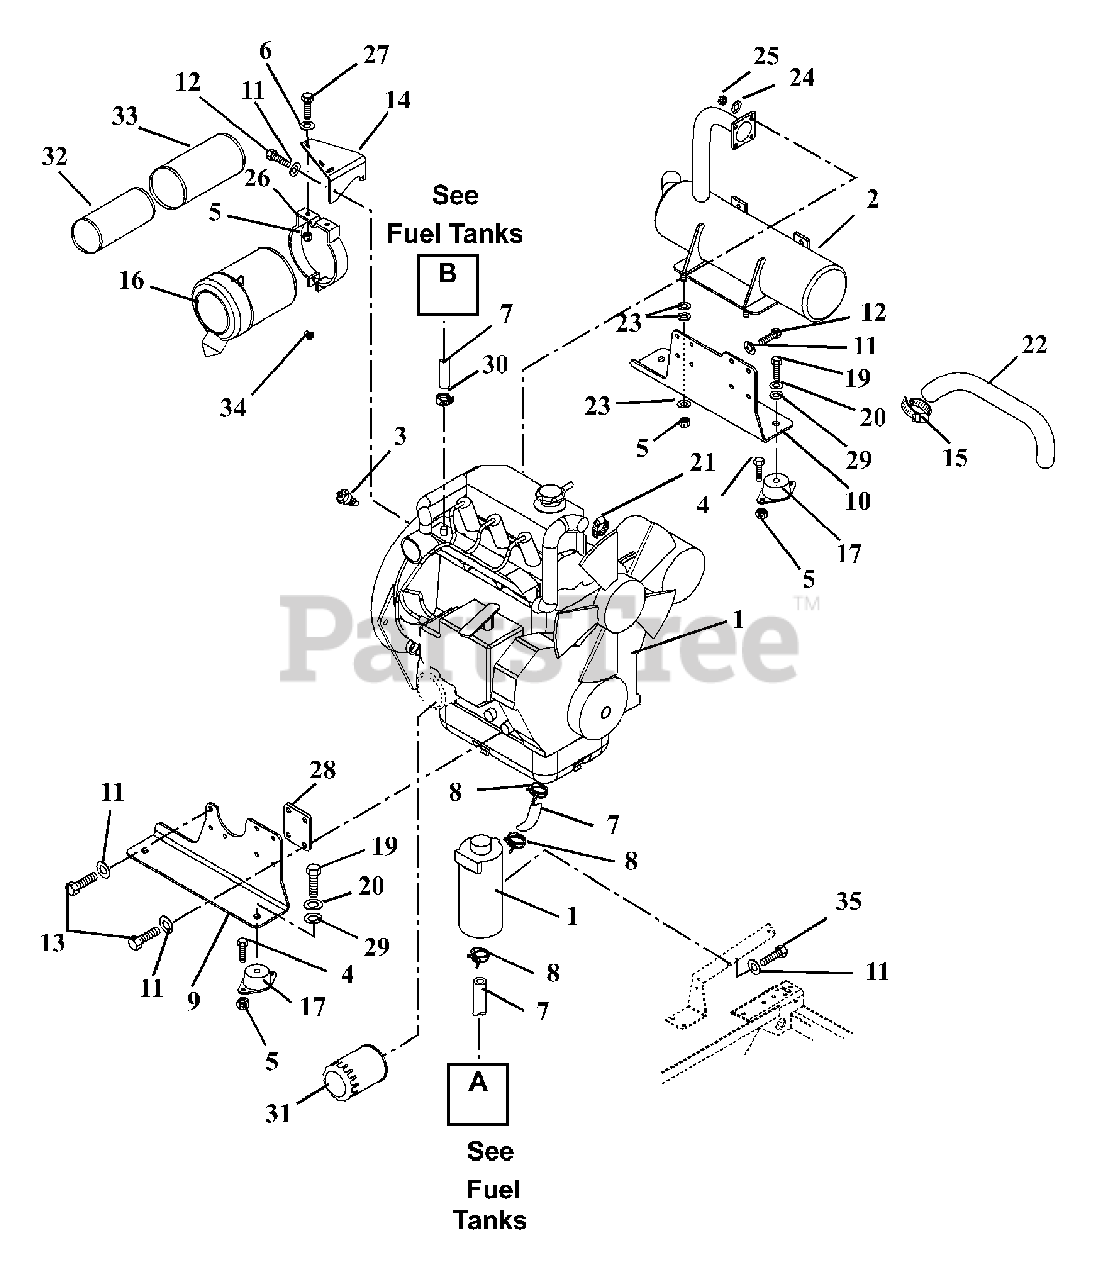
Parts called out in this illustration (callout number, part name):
1	ENGINE, 27HP DIESEL (DAIHATSU)
2	MUFFLER
3	SENDER, TEMPERATURE
4	@BLT-HEX .31-18X.75 GR5 YWZC
5	@NUT-LK-TOP-FLG .31-18 YWZC
6	@WSHR-LK .25X.062 REG YWZC
7	HOSE,5/16 ID
8	CLAMP, HOSE WIRE .520/.550
9	MOUNT, ENGINE RH (DIESEL)
10	MOUNT, ENGINE LH (DIESEL)
11	@WSHR-LK .31X.078 REG YWZC
12	@BLT-HEX M8-1.25X20 YWZC
13	BLT, HEX M8-1.25X25 GR8.8YWZC
14	BRKT, AIR CLEANER - BLACK
15	CLAMP, HOSE #32 (1.56/2.50)
16	AIR CLEANER ASSEMBLY
17	MOUNT, ENGINE, VIBRATION ISO
18	@BLT-HEX .31-18X1.00 GR5 YWZC
19	BLT-HEX .50-20X1.00 GR5 YWZC
20	@WSHR-LK .50X.125 REG YWZC
21	CLAMP-HOSE 1.50X.81X1.42
22	HOSE, AIR CLEANER
23	@WSHR-FL-STL.38X.875X.083 YWZC
24	@WSHR-LK .31X.078 REG YWZC
25	NUT-HEX M8-1.25 YWZC
26	BRACKET, AIR CLEANER MOUNT
27	@WSHR-FL-STL.38X.875X.083 YWZC
28	SPACER, ENGINE MTG (DIESEL)
29	@WSHR-FL-STL.531X1.06X.095YWZC
30	CLAMP, HOSE, IDEAL 6202 SIZE 4
31	FILTER, OIL
32	ELEMENT, INNER SAFETY
33	ELEMENT, OUTER PRIMARY
34	FTG,LUBE 45 DEG
35	@BLT-HEX M6-1X16 YWZC
